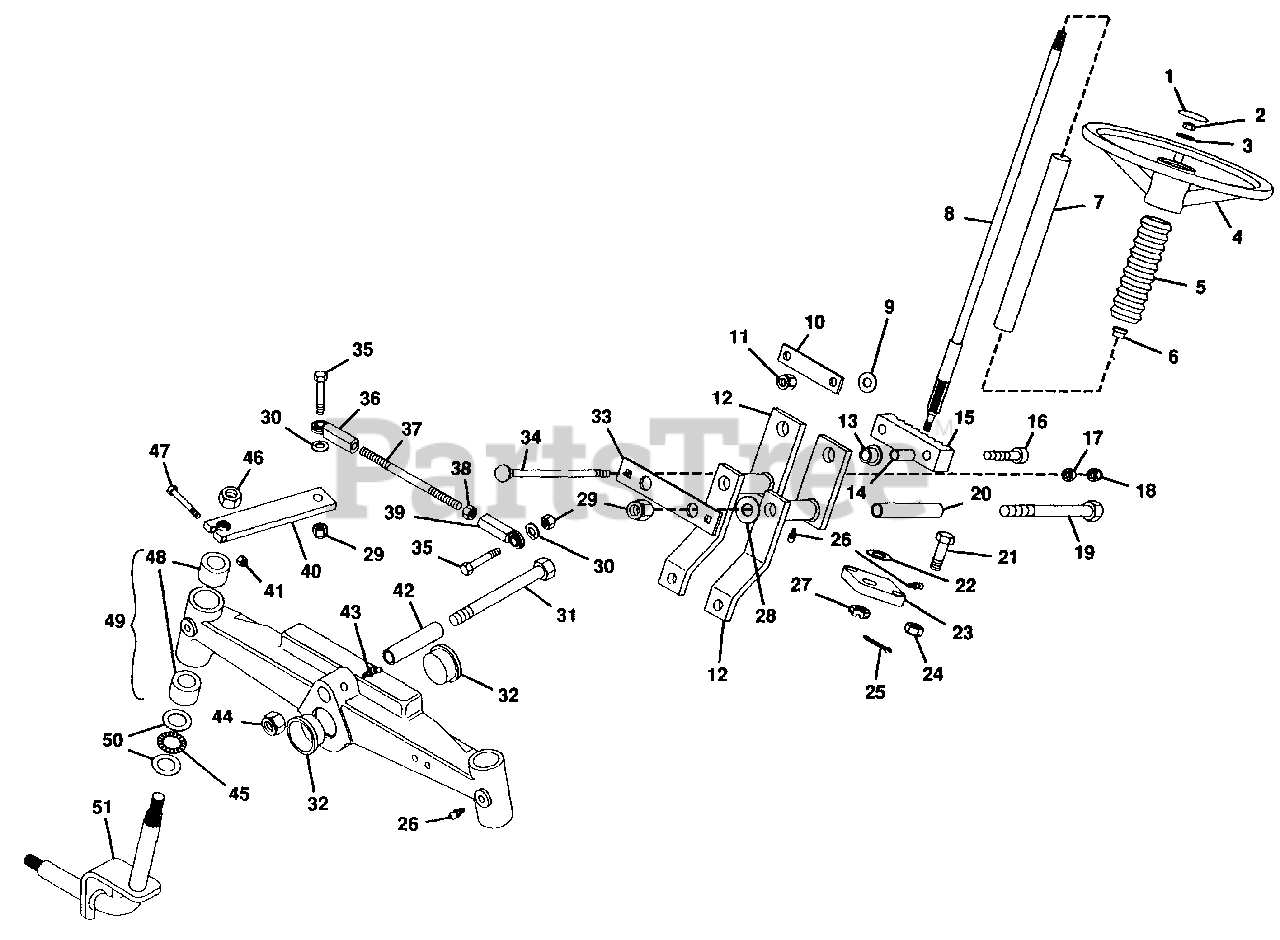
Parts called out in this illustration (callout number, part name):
1	CAP, STEERING WHEEL
2	NUT, JAM 5/8-11 HEX
3	WASHER, FLAT .656X1.312X.095
4	WHEEL, STEERING
5	BELLOWS, STEERING WHEEL
6	BUSHING, NYLON .760X1.00X.60 FLG
7	TUBE, PLASTIC 1.0 I.D.
8	SHAFT, STEERING
9	WASHER, FLAT .375X1.125X.065
10	STRAP, RACK AND PINION
11	NUT, LOCK 3/8-16
12	WELDMENT, STEERING ARM
13	BEARING, FLANGE(P/M BRONZE)
14	BUSHING, .391X.622X.670
15	GEAR, RACK
16	SCREW, CAP 3/8-16X2.0 HSHD
17	NUT, HEX 5/16-18
18	NUT, LOCK 5/16-18
19	BOLT, HEX 1/2-13X6.0
20	SLEEVE, PIVOT
21	BOLT, HEX 7/16-14X1.5
22	RACE, THRUST
23	SUPPORT, STEERING SHAFT
24	NUT, LOCK 7/16-14
25	PIN, COTTER .09X1.00
26	FITTING, LUBE 1/4-28
27	NUT, HEX 1/2-13 SLOTTED
28	RACE, BRG THRUST .752X1.240X.095
29	NUT, LOCK 1/2-13
30	WASHER, LOCK 1/2 REG.
31	BOLT, HEX 3/4-10X4.5
32	CAP, FRONT AXLE
33	PLATE, ADJUSTMENT
34	BOLT, 5/16-18X5.5 RD HD SQ NK
35	BOLT, HEX 1/2-13X2.25
36	ROD END, STEERING R.H.
37	TIE ROD, STEERING
38	NUT, JAM 1/2-20
39	ROD END, STEERING L.H.
40	ARM, TIE ROD AXLE
41	NUT, LOCK 5/16-24
42	TUBE, AXLE PIVOT
43	FITTING, LUBE 45 DEG.
44	NUT, LOCK 3/4-10
45	BEARING, NEEDLE THRUST
46	NUT, HEX 5/8-11
47	BOLT, HEX 5/16-24X1.75
48	BUSHING, .877X1.004X1.0
49	AXLE, STEERING
50	RACE, BEARING THRUST
51	WELDMENT, KING PIN
